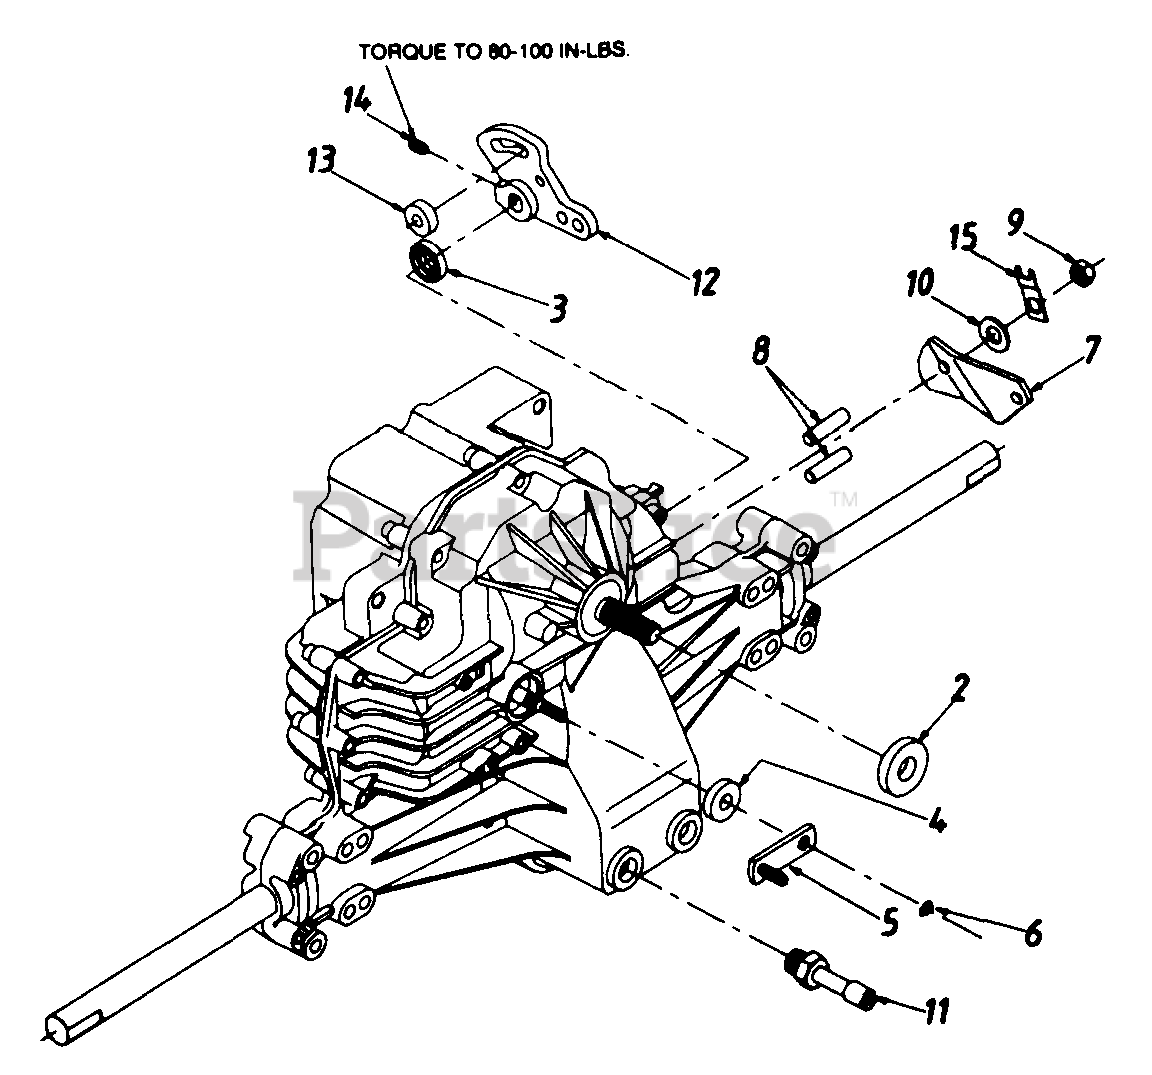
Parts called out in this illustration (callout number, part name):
2	Seal - Lip
3	Seal - Lip
4	Seal - Lip 10 X 25 X 7
5	Arm - Bypass
6	Ring - Retaining
7	Arm - Actuating
8	PIN-ACTUATING
9	Nut - Hex Lock 5/16-24 UNJC
10	Washer 7/16" x 7/8" x .060"
11	Breather Ass'y.
12	Arm - Control
13	Puck - Dampener
14	Set Screw
15	Strap, Locking
